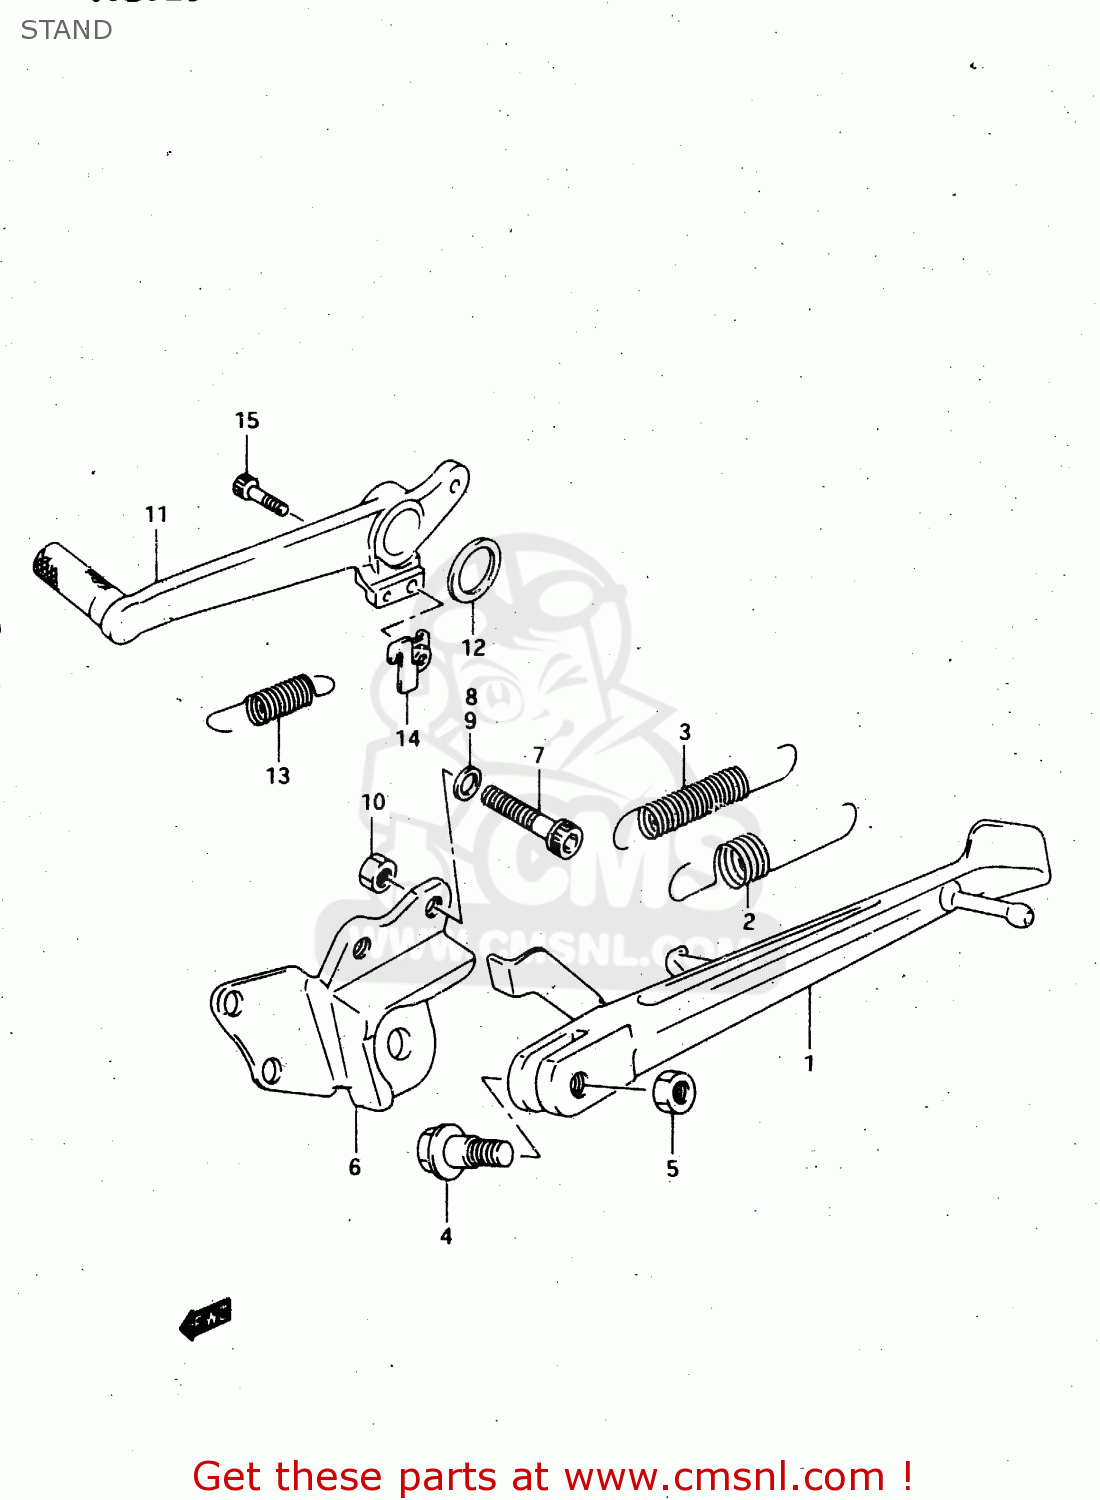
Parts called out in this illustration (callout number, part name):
1	STAND, PROP
2	SPRING
3	SPRING
4	BOLT(10X30)
5	NUT
6	BRACKET, PROP STAND
7	BOLT
8	WASHER
9	WASHER
10	NUT
11	PEDAL,BRAKE
12	WASHER(18X24X1)
13	SPRING
14	BRACKET,STOP LAMP SWITCH SPR
15	SCREW
